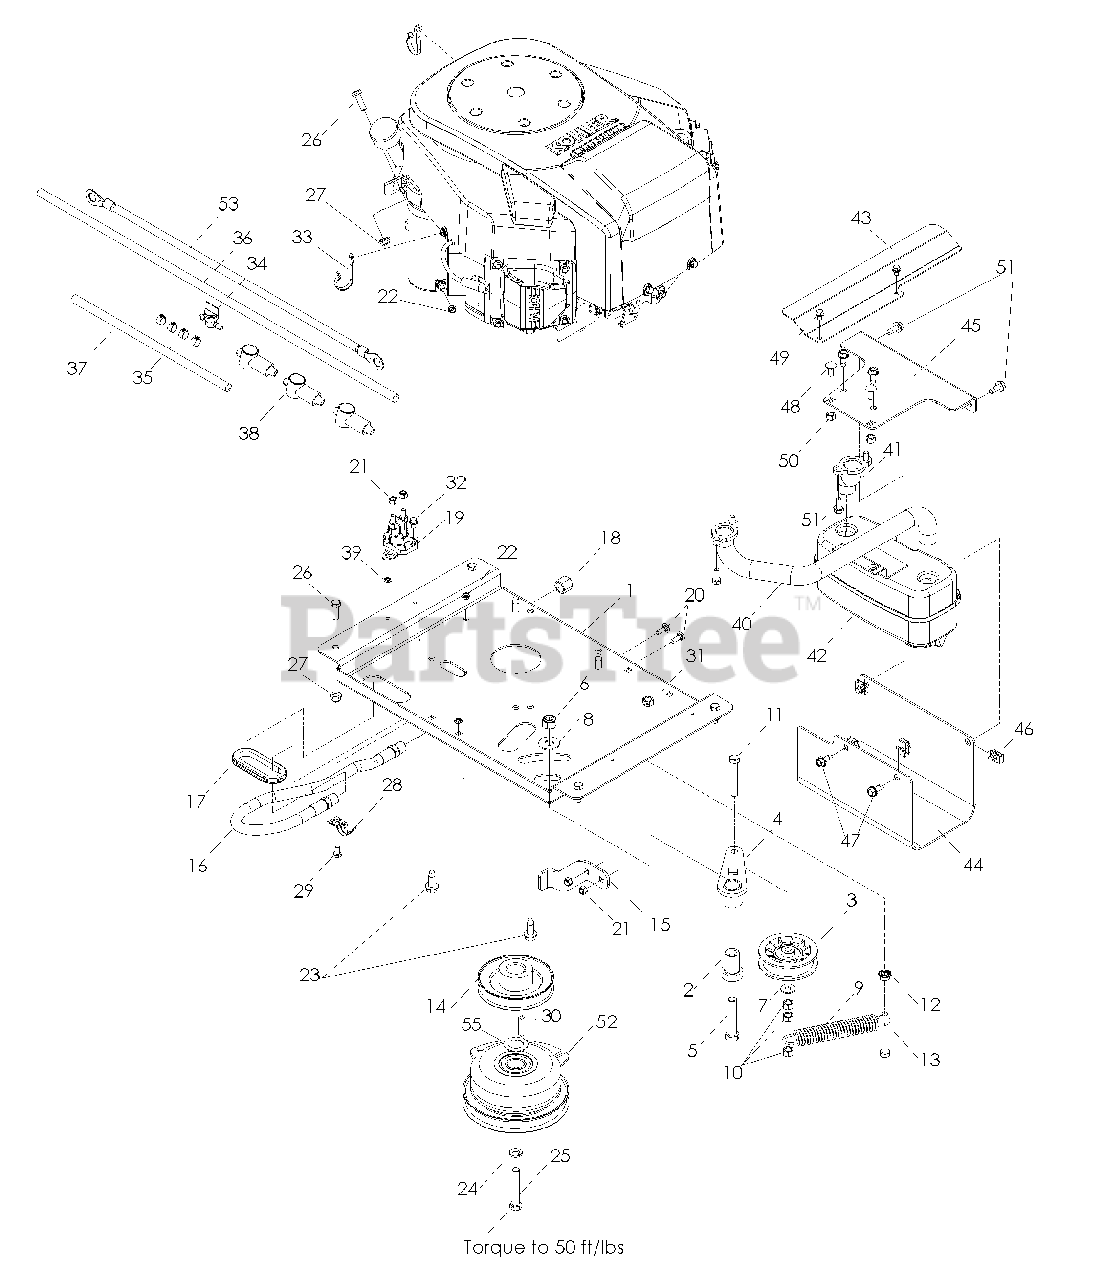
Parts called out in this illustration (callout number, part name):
1	PLATE, ENGINE
2	IDLER SPINDLE
3	IDLER PULLEY
4	IDLER ARM WLDMT
5	HCS 1/2-13 x 2 1/2
6	NUT 1/2 HEX NYLOC
7	WASHER, 5/16 STD FLT
8	WASHER, 1/2 STD FLT
9	TRACTION SPRING
10	NUT 3/8-16 HEX NYLOC
11	HCS 3/8-16 x 2 1/2 TPBLT
12	NUT 3/8-16 HEX WHIZLK
13	HCS 3/8-16 x 2 3/4
15	TIE DOWN, CLUTCH
16	DRAIN, OIL
20	RHSNB 1/4-20 x 3/4 GR2 ZN
21	NUT 1/4-20 HEX NYLOC
22	NUT 1/4-20 HEX THIN NYLOC
23	BOLT 3/8-16 x 1 THD FRM
24	WASH 7/16 SLW
25	HCS 7/16-20 x 2 1/2
26	HCS 5/16-18 x 1
27	NUT 5/16-18 FLANGE NYLOC
29	HCS 1/4-20 x 1/2
30	KEY 1/4 SQ x 1 1/4
31	NUT 3/8-16 HEX CNTRLK
32	SCREW 1/4-20 x 3/8 THD FRM
34	FUEL VALVE
35	HOSE CLAMP
36	FUEL LINE-30"
37	FUEL LINE-13"
39	WASHER 1/4 INT TOOTH LK
40	MANIFOLD, FT
41	MANIFOLD, RR
42	MUFFLER ASM TWIN
43	SHIELD, HEAT
44	GUARD, MUFFLER
45	MOUNT, MUFFLER
46	RETAINER, U TYPE
47	BOLT 5/16-18 x 3/4 THD FRM
48	RHSNB 5/16-18 x 3/4
49	SCREW 1/4-20 x 3/8 THD FRM
50	NUT 5/16-18 HEX NYLOC
51	HCS 5/16-18 x 3/4
52	CLUTCH, MODELS: 968999717, 968999720, 968999748
53	CLUTCH, MODELS: 968999718, 968999719, 968999721, 968999749, 968999780
54	CABLE, POSITIVE
55	WASHER, 1.025ID X 1.64OD
